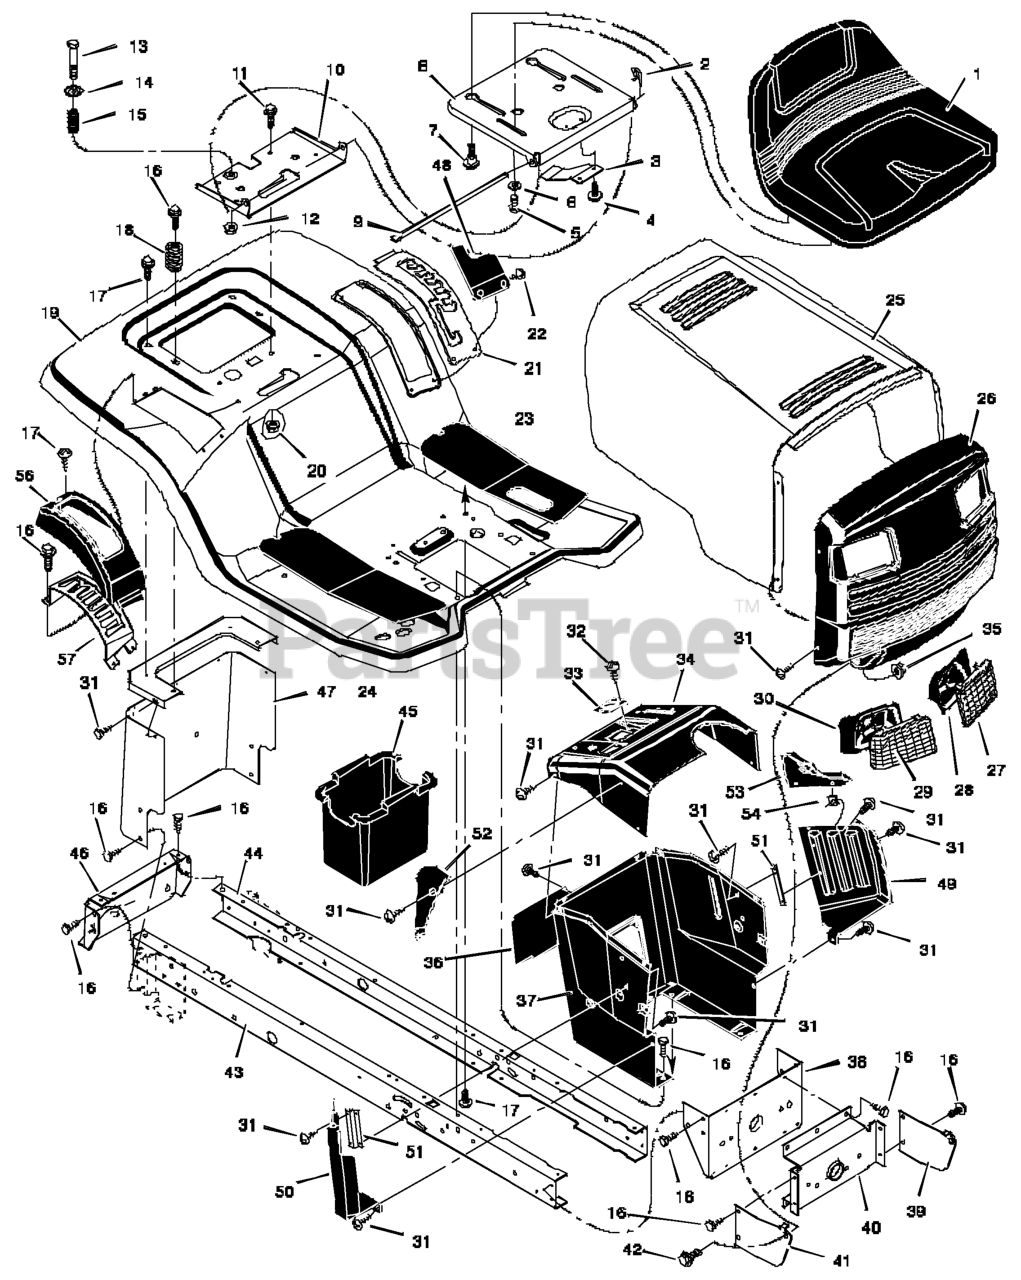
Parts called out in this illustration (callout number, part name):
2	Cap, Push On
5	Bolt, Wing
6	Washer
7	Bolt, Shoulder
8	Support, Seat
9	Rod, Pivot
10	Bracket, Pivot
11	Bolt
13	Bolt, Shoulder
15	Spring
19	Deck, Seat
20	Nut
21	Plate, Index
23	Mat, Left
24	Mat, Right
27	Lens, Left
28	Bezel, Left
29	Lens, Right
30	Bezel, Right
31	Screw
33	Bearing, Steering
35	Nut
36	Panel, Access
37	Support, Dash
38	Bracket, Rear Hanger
39	Support, Left Grille
40	Axle, Hanger
41	Support, Right Grille
42	Bolt, Shoulder
43	Frame, Right
44	Frame, Left
45	Container, Battery
46	Plate, Hitch
47	Panel, Rear
48	Cover, Level Adjustment
49	Panel, Left Side
50	Panel, Right Side
51	Bracket, Panel
52	Cap, Panel
53	Cap, Left Panel
54	Retainer
55	Plate, Rear
56	Cover, Shift Gate
57	Shift Gate
